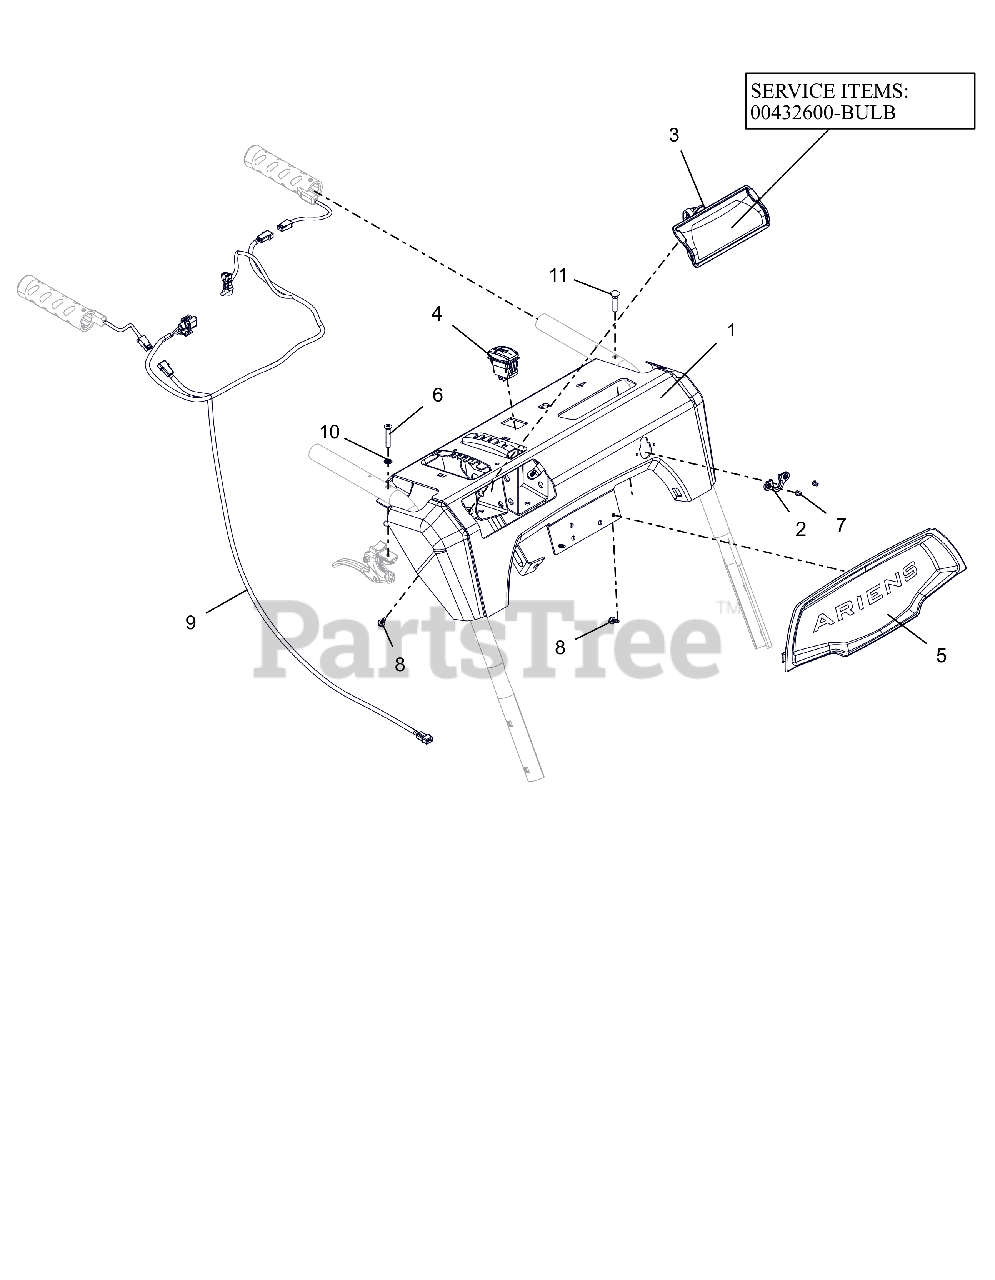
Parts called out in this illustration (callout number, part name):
1	CONTROL PANEL W/DECAL FRIC-TRK
2	GROMMET, CABLE, QUICK TURN 2
3	HEADLIGHT ASY, HALO 20W 2SHOT
3	BULB, LIGHT-HALOGEN 20W
4	SWITCH,ROCKER SPST-ON/OFF
5	BEZEL, DASH - ARIENS LG DASH
6	SCR-MCH .25-20X1.50 OVAL HD
7	RVT-POP #43 .125X.313 STL ZINC
8	SCR-TAP #10X.50 BOSS INDHXHD
9	HARNESS, LIGHT & WARMER
10	WSHR-LK-INT .250 TH TYA
11	BLT-RDHDXLSQNK.25-20X1.25 G5ZC
